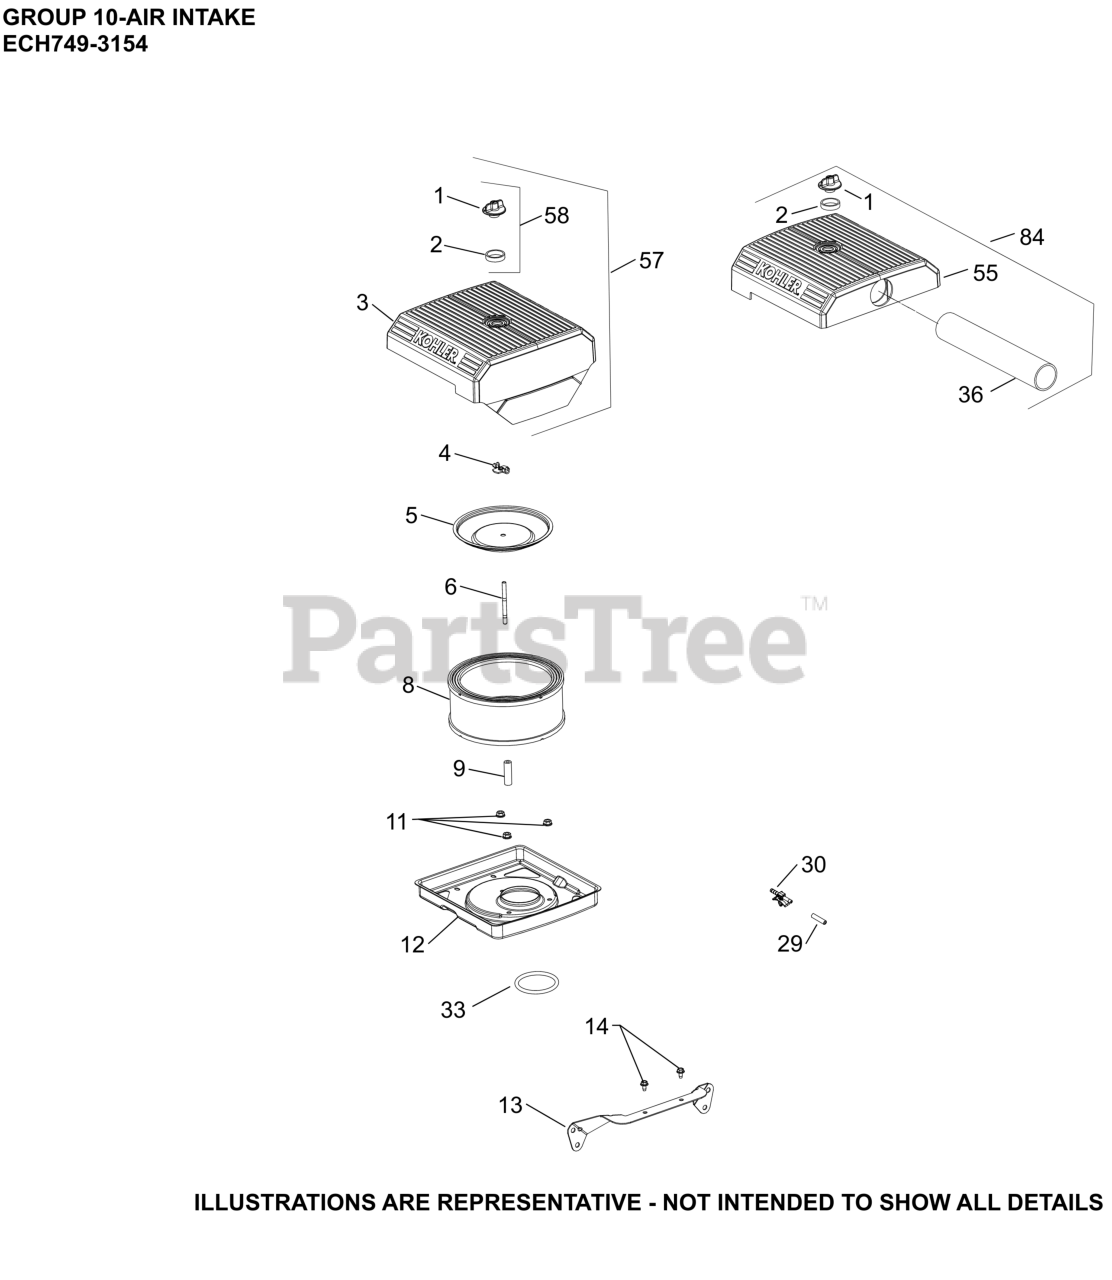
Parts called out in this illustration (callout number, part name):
1	KNOB, COVER
3	COVER, AIR CLEANER
4	NUT, WING
5	COVER, INNER AIR CLEANER
6	STUD, LOW PROFILE A/C
8	AIR FILTER ELEMENT
11	NUT, FLG M6X1.0
12	BASE, AIR CLEANER
13	AIR CLEANER BRACKET
14	SCREW, THREAD FORMING
29	CAP, MASKING
30	CONNECTOR, EVAPORATIVE
33	O-RING, AIR CLEANER BASE
36	HOSE, HEATER
55	COVER, AIR CLEANER
57	KIT, AIR CLEANER COVER
58	KIT, KNOB W/SEAL
84	COVER, AIR CLEANER
